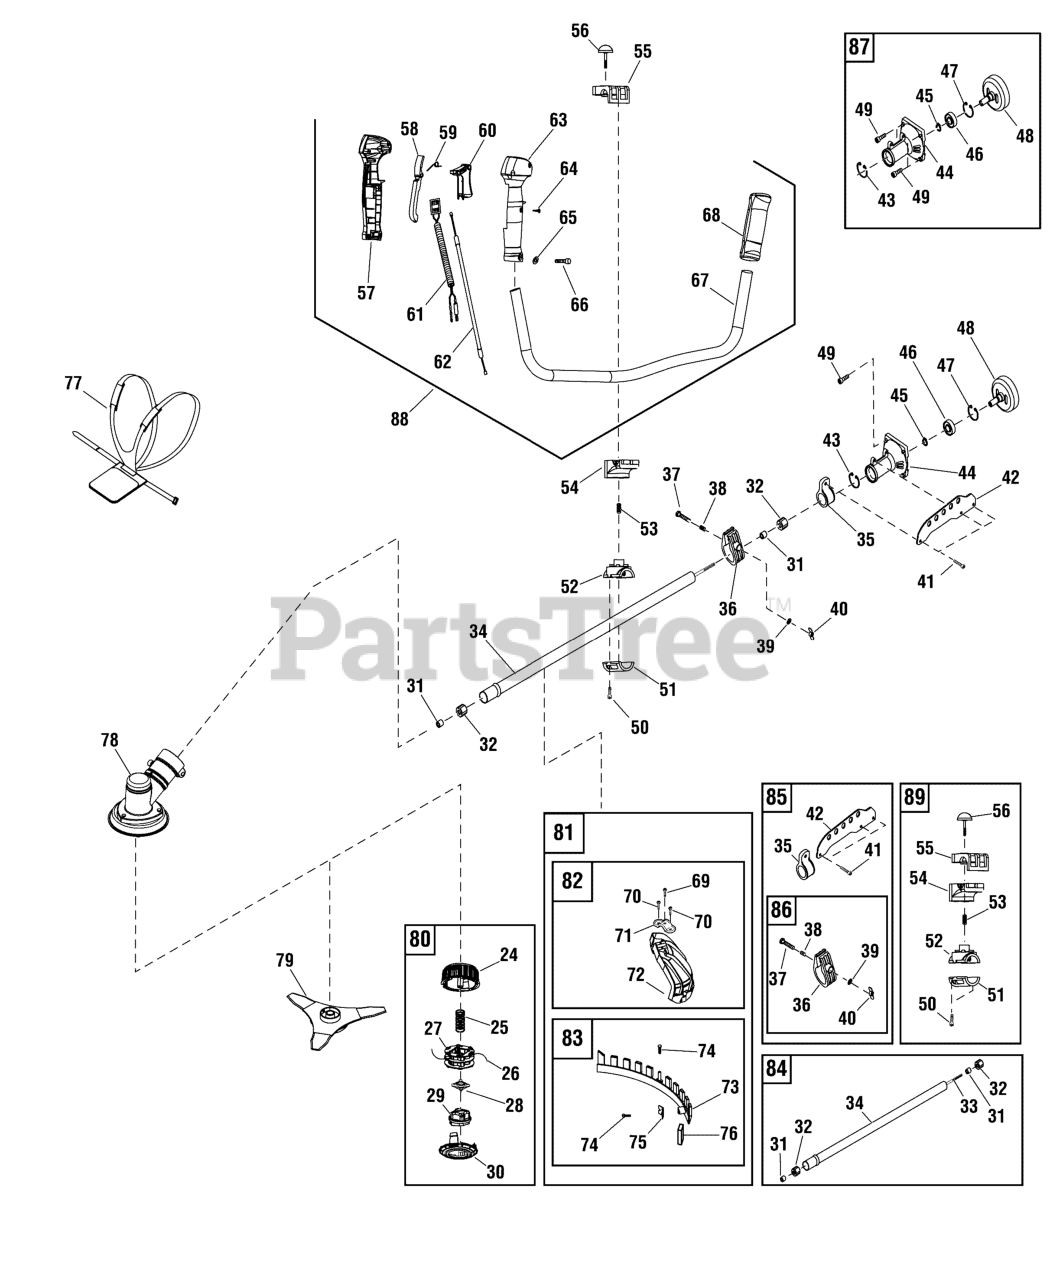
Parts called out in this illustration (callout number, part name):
24	BOX, Bump Head
25	SPRING, Bump Head
26	ROPE, Flexible
27	SEAT, Flexible Rope
28	COVER, Flexible Rope
29	BUMP HEAD
30	COVER, Bump Head
31	BEARING, Oil
32	RUBBER COVER, Bearing Oil
33	DRIVE SHAFT
34	SHAFT, Straight
35	RING, Hang
36	RING, Limit
38	SPRING
41	BOLT, M6 x 16
42	HANDLE, Hang
44	CASE, Clutch
48	CLUTCH DRUM, Complete
51	BRACKET, Shaft, Lower
52	BRACKET, Shaft, Upper
53	SPRING
54	BRACKET, Handle, Lower
55	BRACKET, Handle, Upper
56	BOLT, With Knob, Red
57	COVER, Handle, Control Switch, LH
58	HANDLE, Self Lock
59	SPRING, Torsion
60	LEVEL, Throttle
61	STOP BUTTON, Complete
62	CABLE, Complete
63	COVER, Handle, Control Switch, RH
64	SCREW, Self Tapping, M3.5 x 13
65	WASHER, Flat, 5
66	SCREW, M5 x 30
67	HANDLE
68	COVER, Handle
69	BOLT, M5 x 10
70	BOLT, M5 x 12
71	HOLDER, Safety Guard
72	SAFTEY GUARD
73	SECURING SADDLE
74	SCREW, Self Tapping, ST4.2 x 16
76	COVER, Blade
77	SHOULDER BELT
78	KIT, Gear Box
79	KIT, Blade
80	KIT, Bump Head
81	KIT, Guard Assembly
82	KIT, Blade Guard
83	KIT, Securing Saddle
84	KIT, Drive Shaft
85	KIT, Hang Handle
86	KIT, Limit Ring Assembly
87	KIT, Clutch Assembly
88	KIT, Handle Assembly
89	KIT, Handle Bracket Assembly
